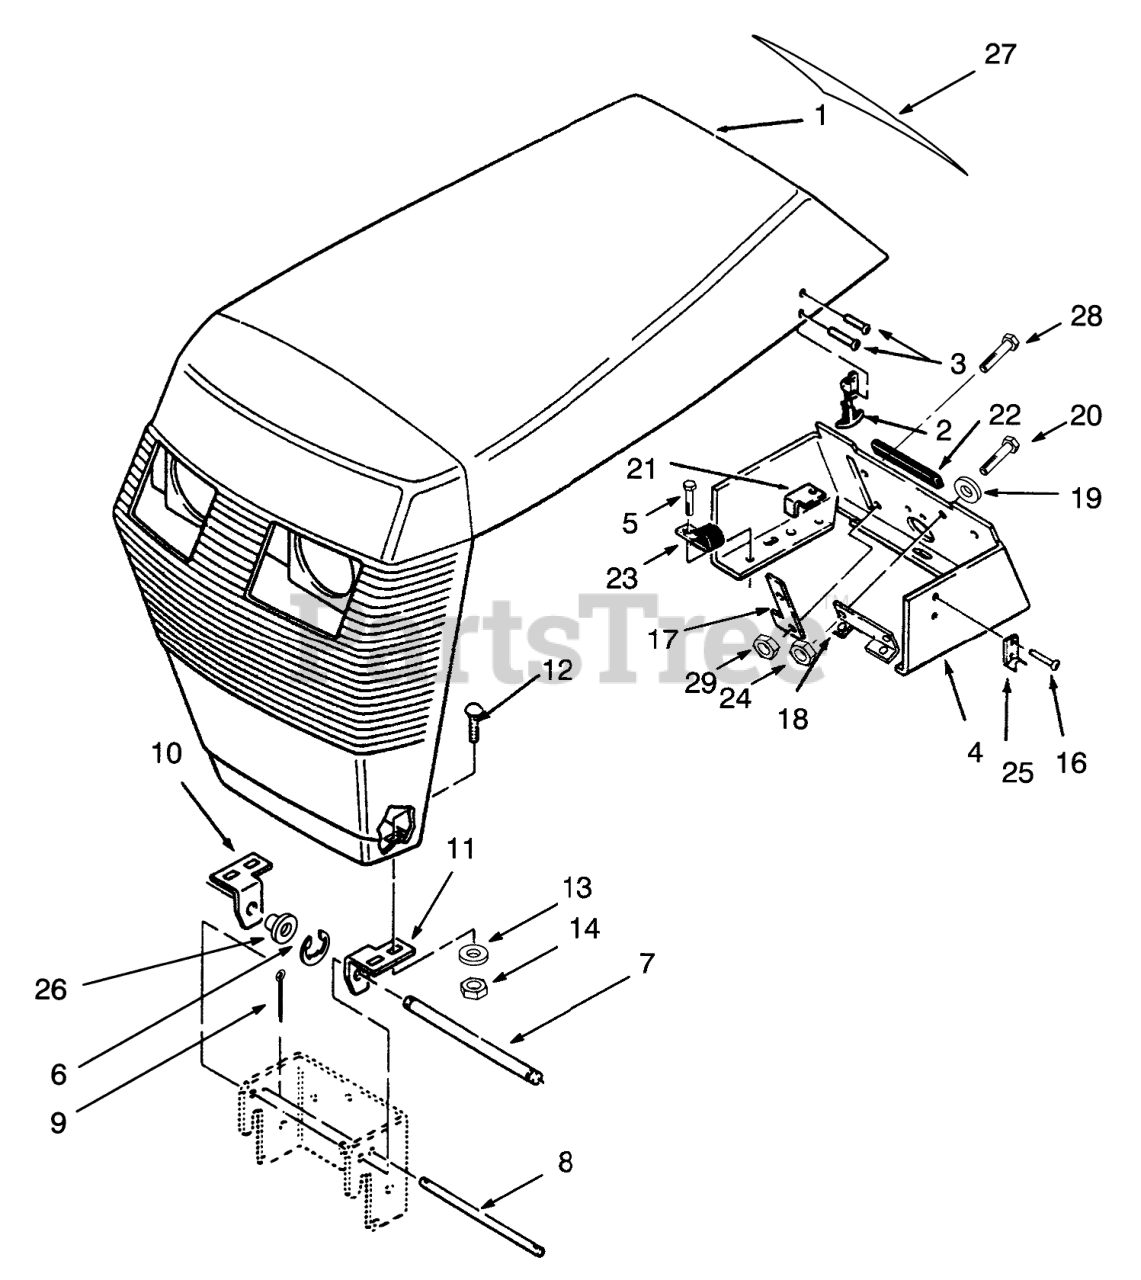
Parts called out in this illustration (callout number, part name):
1	Hood (Incl. Ref. #27)
2	Handle Assembly (Incl. Ref. #25)
3	RIVET-POP
4	CONSOLE B
5	Bolt
6	RING-RETAINING
7	ROD-GRILL PIVOT
8	ROD-HOOD STOP
9	Pin-Cotter
10	BRACKET-GRILL, R H
11	BRACKET-GRILL, LH
12	SCREW-CARR
13	WASHER-FLAT
14	NUT-LOCK
16	POPRIVET 1/8X 1/8 BK
17	Washer
18	BRACKET
19	Washer-Lock
20	SCREW-PAN
21	STOP-PTO
22	EDGING-CONSOLE
23	J-CLIP
24	Nut
25	KEEPER-LATCH
26	BUSHING-NYLINER
27	Decal-Danger
28	SCRW-PHC
29	Nut
